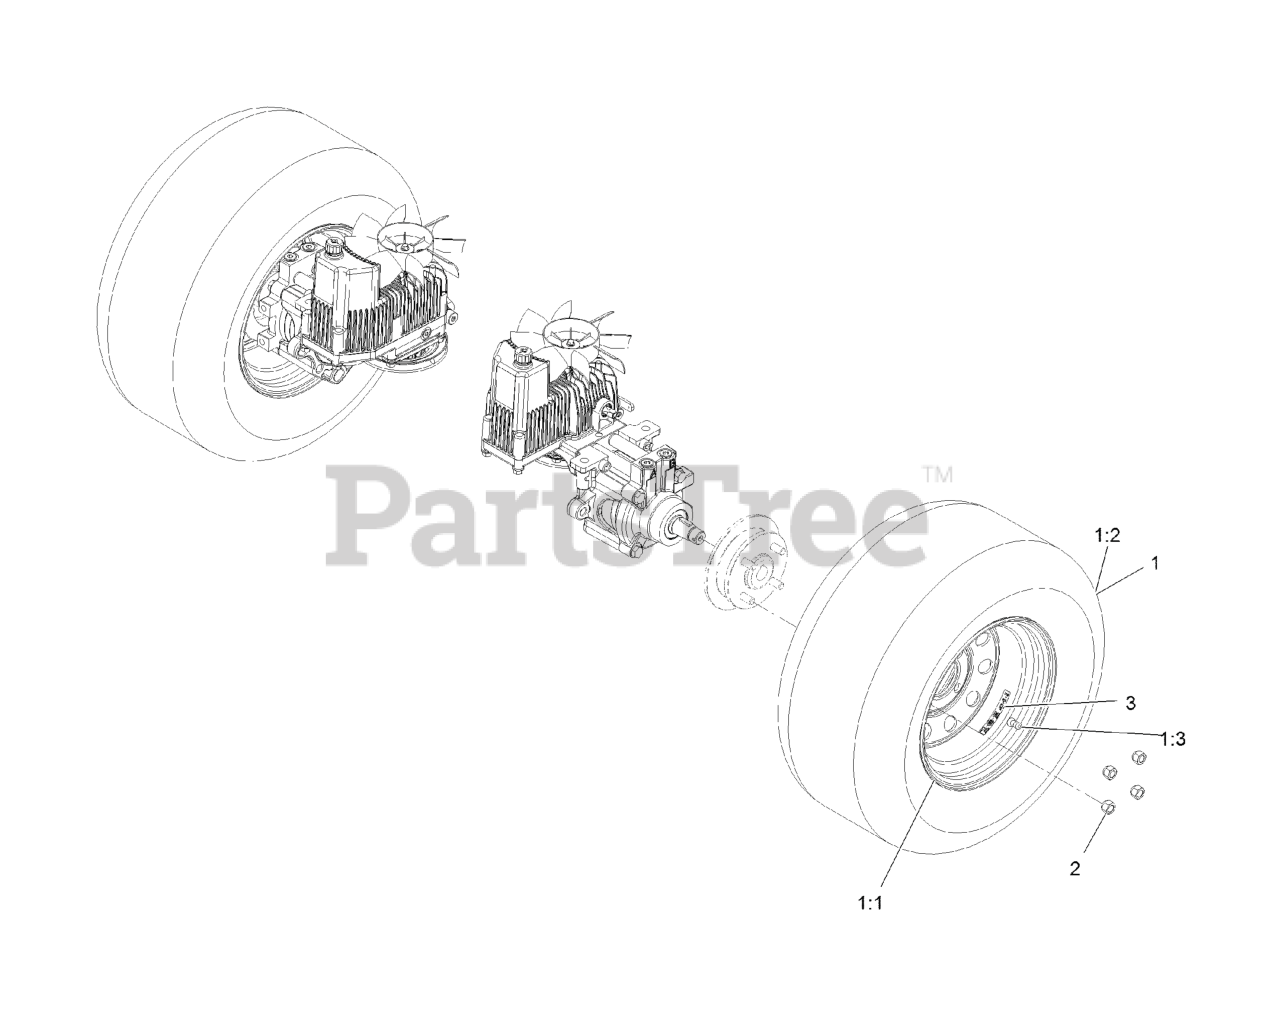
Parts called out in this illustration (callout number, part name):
1	ASM-WHEEL AND TIRE
1:1	ASM-RIM 60
1:2	TIRE-DRIVE
1:3	Stem-Valve
2	NUT-LUG
3	DECAL-TORQUE, WHEEL HUB LUG
